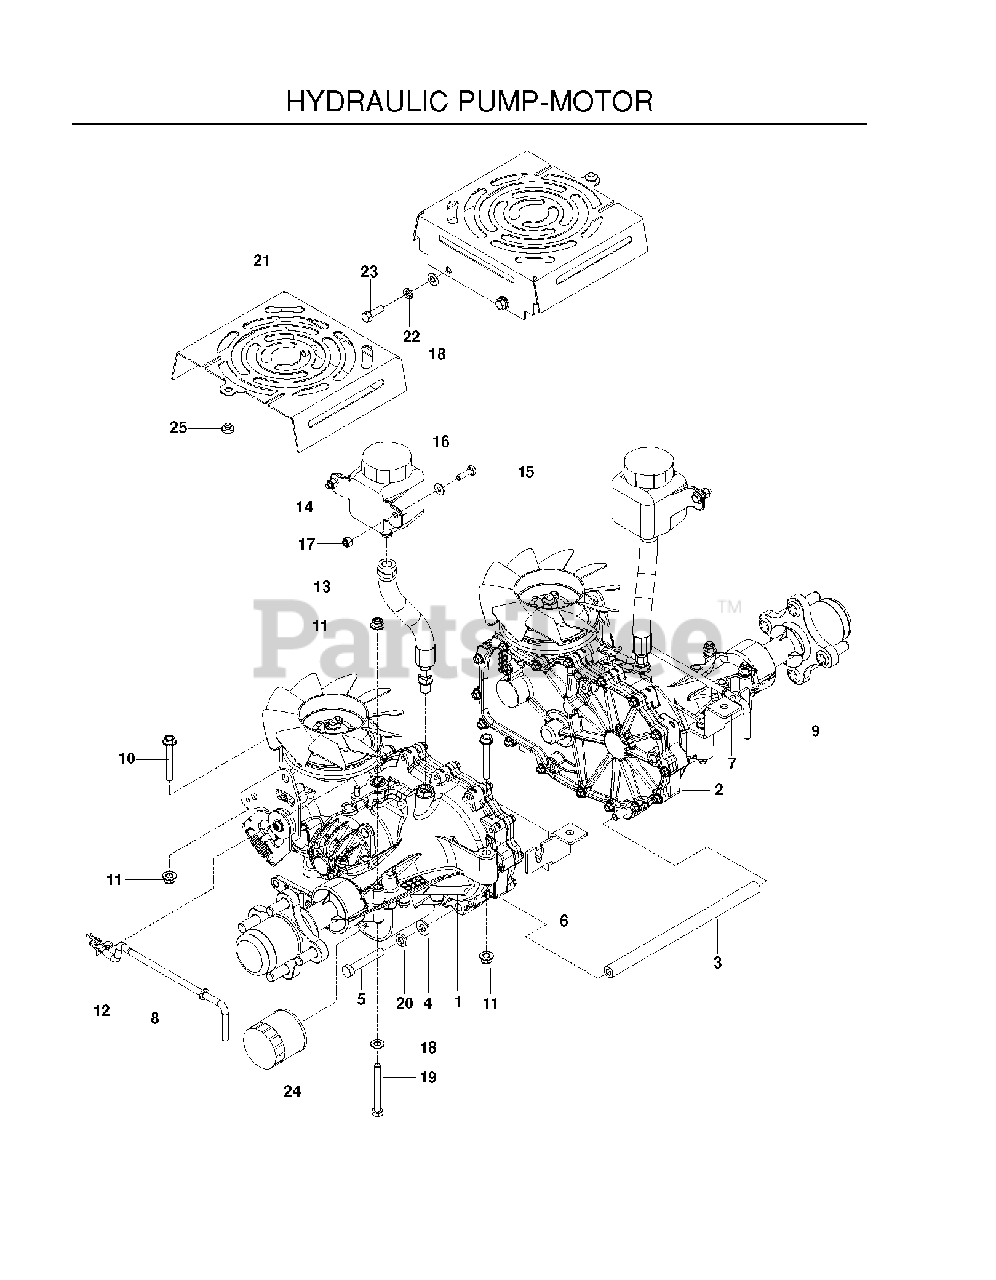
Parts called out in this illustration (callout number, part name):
3	TUBE, SPACER, 3400
4	WASHER 3/8 SAE FLAT
5	HCS 3/8-16X2-1/4 LOC PATCH GR8
8	LINKAGE, LEFT BYPASS
9	LINKAGE, RIGHT BYPASS
10	HHFS 5/16-18 X 2.25 GD 5
11	5/16-18 NYLOC FLANGE NUT
12	HAIRPIN #2
13	HOSE ASSY, EXPANSION
14	TANK, EXPANSION, 350ML
15	HCS 1/4-20X7/8 GR5
16	WASHER 1/4 SAE
17	NUT 1/4-20 NYLOC
18	FLAT WASHER 5/16 SAE
19	HCS 5/16C X 2-3/4
20	SLW 3/8 STD
21	SHIELD, FAN, BLK
22	WASHER 5/16 LOCK
23	HCS 5/16C X 1
24	FILTER, ZT4800
25	GROMMET, BUMPER
